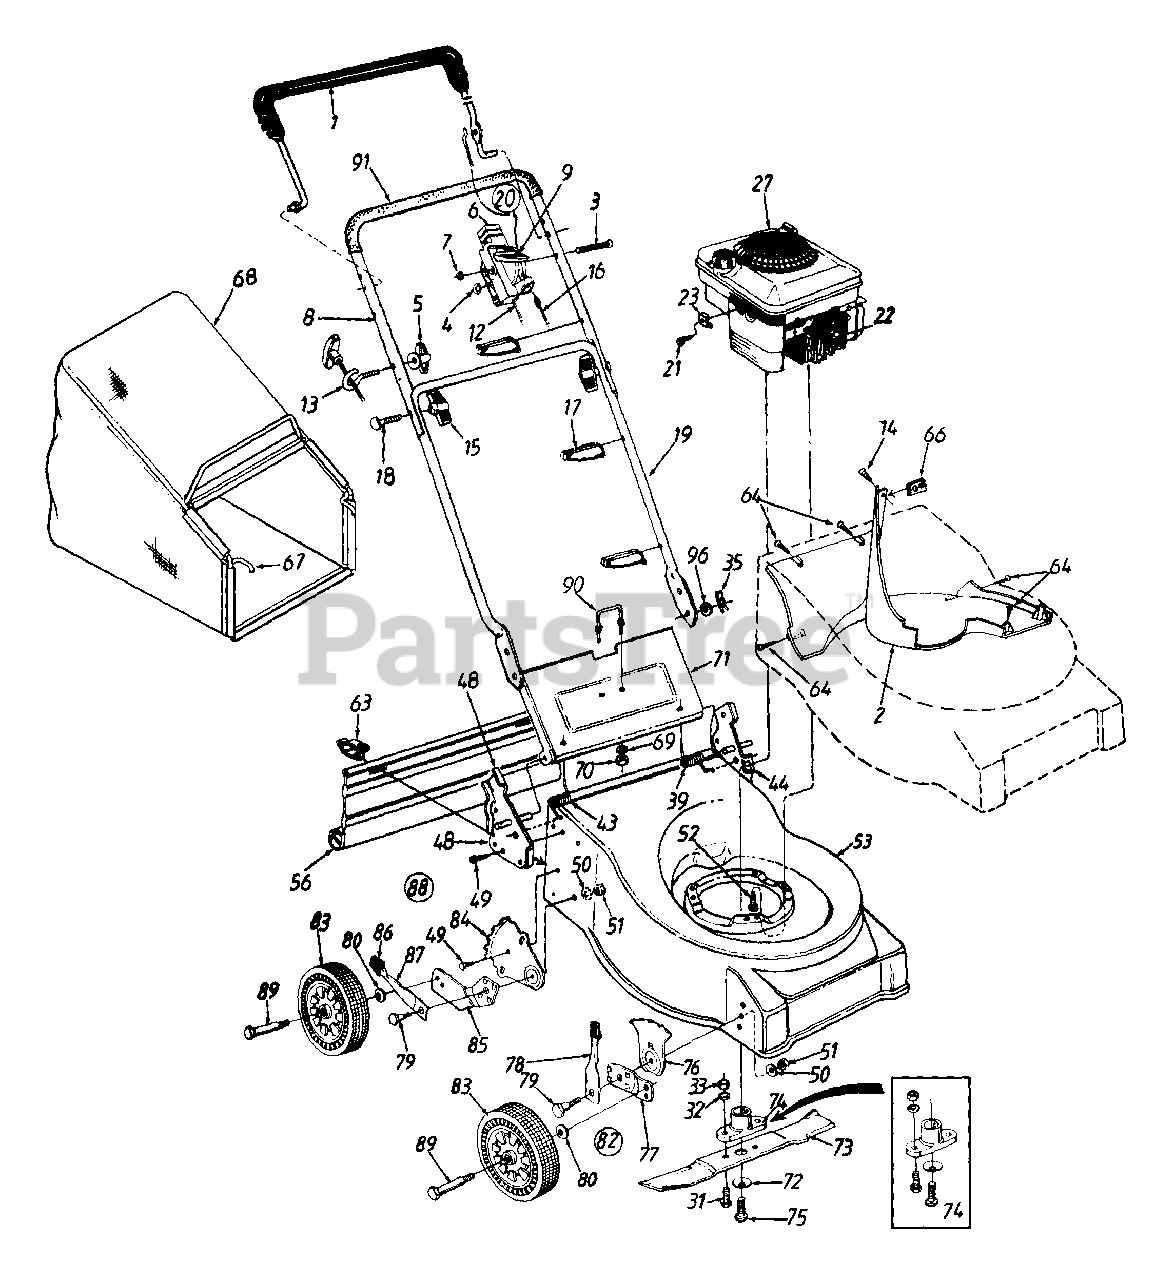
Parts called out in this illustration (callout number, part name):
1	Control Handle Ass'y
2	Rear Baffle
3	Oval C-Sunk Mach. Scr.
4	Spr. Wash. .66" I.D.
5	Wing Nut 1/4-20 Thd.
6	Throttle Body
7	Hex L-Nut 1/4-20 Thd.
12	Throttle Control Wire - 60"
14	Recess Hd. B-Tap Scr. #10-16 Thd.
15	Hand Knob
16	Control Cable - 47"
17	Cable Tie
18	Curved Hd. Bolt 5/16-18 x 2" Lg.
20	Throttle Box Comp.
21	Hex Self-Tap Scr. #10-32 x .62"
22	Spark Plug Boot
23	Casing Clamp
27	Engine
31	Hex Bolt 3/8-24 x 1" Lg.
32	L-Wash. 3/8" I.D.
33	Hex Nut 3/8-24 Thd.
35	Int. Cotter Pin 5/16" Dia.
39	Torsion Spring - L.H.
43	Torsion Spring - R.H.
44	Handle Brkt. Ass'y. - L.H.
48	Handle Brkt. Ass'y. - R.H.
49	Hex L-Wash. AB-Tap Scr. 1/4 x .62" Lg.
50	Bell-Wash. .39" I.D.
51	Hex Nut 3/8-16 Thd.
52	Hex L-Wash. Hd. Scr. 3/8-16 x 1" Lg.
63	Hinge Clip
64	Truss Mach. Scr. #12 x 1" Lg.
66	"U"-Nut #10-16 Thd.
69	L-Wash. 5/16" I.D.
70	Hex Nut 5/16-18 Thd.
74	Blade Adapter Kit
75	Hex Bolt 3/8-24 x 1.5" Lg.
76	Height Adj. Plate
78	Spring Lever Ass'y. w/Knob
79	Shld. Bolt .50" Dia. x .357"
80	Bell-Wash. .38" I.D. x .88" O.D.
82	Height Adj. Ass'y. Comp. - R.H.
83	Wheel Ass'y. Comp.
84	Index Plate
85	Pivot Bar - R.H.
86	Spring Lever Knob
88	Rear Height Adj. Ass'y. Comp. - R H.
90	Chute Door Handle
91	Foam Grip
96	Bell-Wash. .38" I.D.
